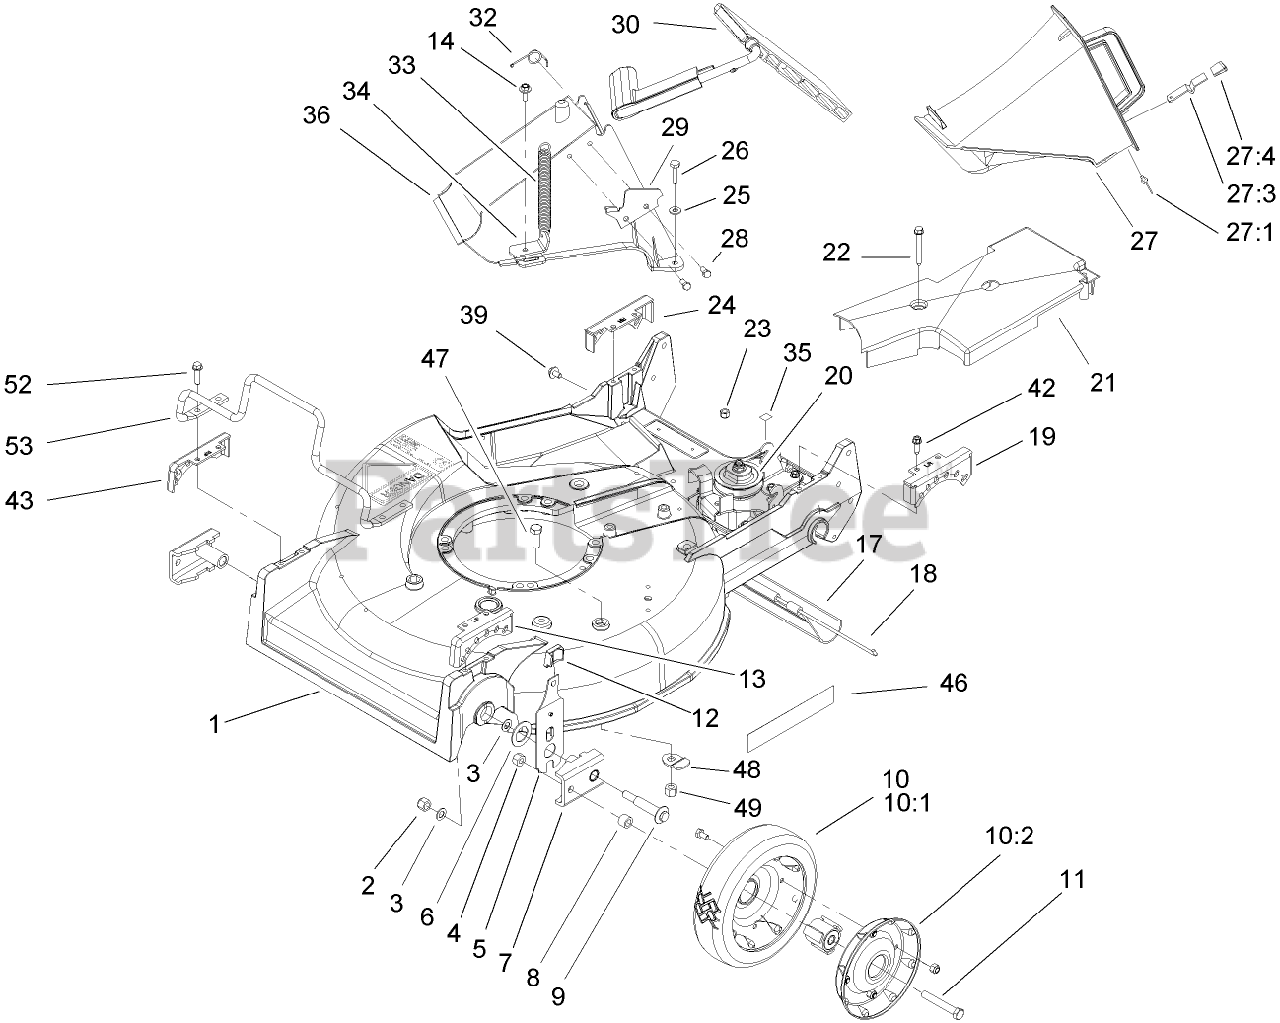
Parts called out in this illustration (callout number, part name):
1	HOUSING
2	NUT-LOCK
3	WASHER
4	NUT-LOCK, CONE
5	FRONT SPRING ARM ASM
6	WASHER-THRUST
7	ARM-PIVOT, FRONT
8	SPACER-WHEEL
10:2	Wheel ASM
11	SCREW-HH
12	KNOB-ARM
13	QUADRANT-FRONT, LH
14	SCREW-HWH
18	ROD-SHIELD
19	QUADRANT-REAR, LH
21	COVER-BELT
22	SCREW-HWH
23	NUT-LOCK, NI
24	QUADRANT-REAR, RH
25	WASHER-FLAT
26	SCREW-HH
27	DISCHARGE PLUG ASM
27:1	RIVET-HEAD, FLAT
27:3	LATCH-PLUG, DISCHARGE
27:4	GRIP-LATCH
28	SCREW-PLASTITE
29	LATCH-PLATE
30	DISCHARGE DOOR ASM
32	RETAINER-DOOR
33	SPRING-DOOR
34	BRACKET-SPRING
35	DECAL-GREASE
36	TUNNEL-DISCHARGE
39	SCREW AND WASHER ASM
42	SCREW-HWHTF
43	QUADRANT-FRONT, RH
47	SCREW-HH
48	SHIELD-RETAINER
49	NUT-LOCK, NI
52	SCREW-HWHTF
53	GUARD-ENGINE
